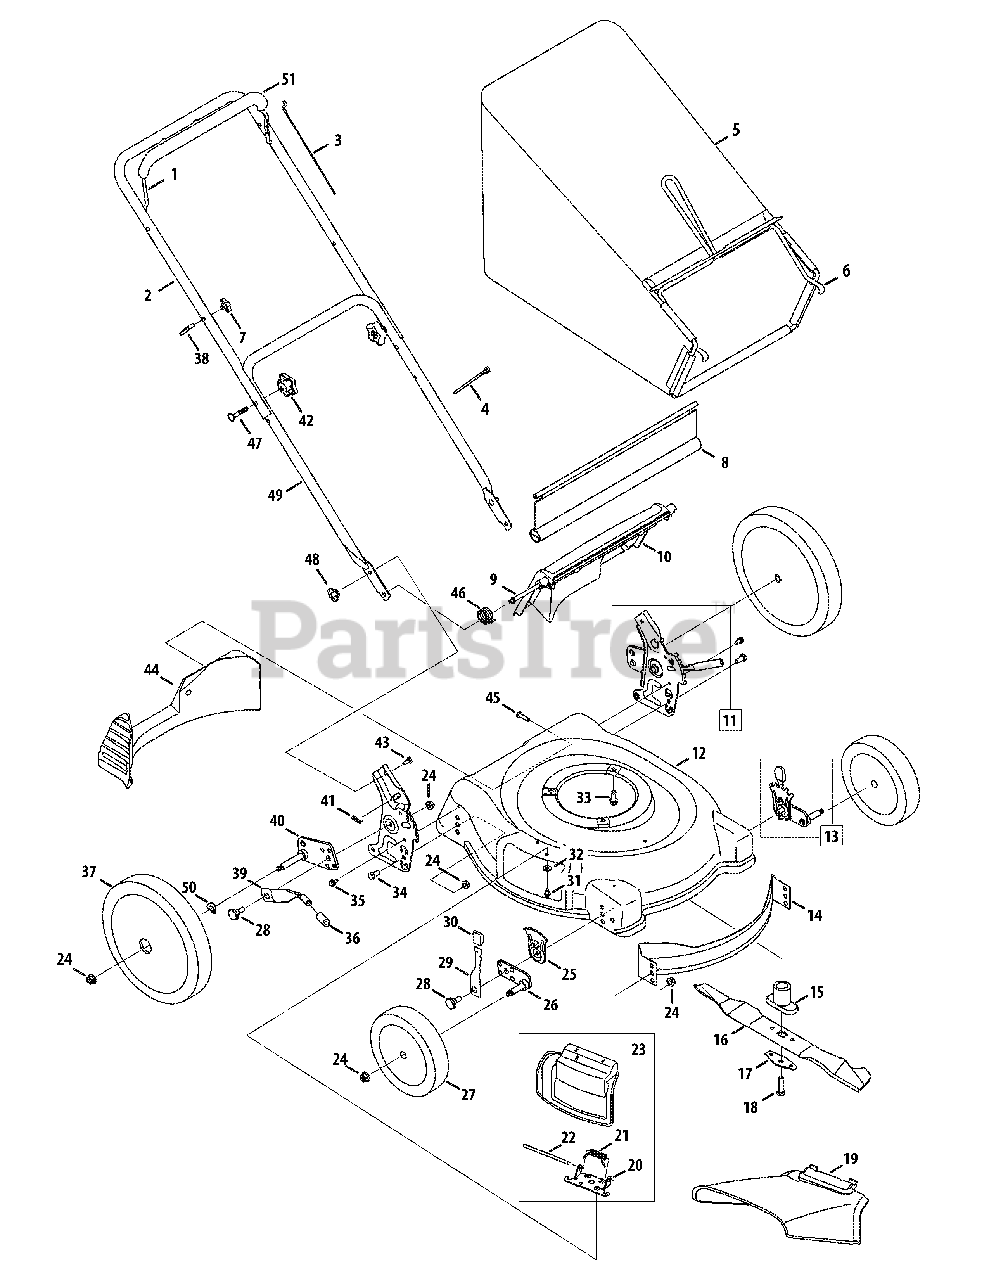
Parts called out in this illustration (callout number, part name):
1	Blade Control
3	Control Cable, 40"
4	Cable Tie
5	Grass Bag
7	Handle Knob
8	Trailshield
10	Rear Discharge Door
11	Rear Handle Bracket Assy. - LH
11	Rear Handle Bracket Assy. - RH
12	Deck 21-inch
13	Front Hgt. Adj. Assy., 8" Whl. - LH
13	Front Hgt. Adj. Assy., 8" Whl. - RH
14	Front Baffle
15	Blade Adapter - 25mm
16	21-inch Mulching Blade
17	Bell Blade Support
18	Hex Screw, 3/8-24 x 2.5
19	Side Discharge Chute
20	Deflector Chute Adaptor
21	Torsion Spring
22	Hinge Pin
23	Mulch Plug Assembly
24	Flange Lock Nut 3/8-16
25	Height Adjustment Plate
26	Pivot Arm Assy RH (8" wheel)
26	Pivot Arm Assy LH (8" wheel)
27	Front Wheel
28	Shoulder Scr., .5D x .385
29	Front Spring Lever
30	Height Adjust Knob
31	TT Screw, 1/4-20 x .500
32	Bell Washer
33	TT Screw, 3/8-16 x 1.0
34	Hex Screw, 3/8-16 x .75
35	TT Screw, 1/4-20 x .625
36	Foam Grip
37	Rear Wheel
39	Rear Hi-Wheel Spring Lever
40	Rear Pivot Arm Assy - RH
40	Rear Pivot Arm Assy - LH
41	Hairpin Clip
42	Star Knob
43	Carriage Bolt ,1/4-20 x .75
45	Screw HL, 1/4-15 x 1.00
46	Torsion Spring - RH
47	Carriage Bolt, 5/16-18 x 2
48	Wing Nut
50	Spring Washer
51	Deluxe Bail Cover - Red
